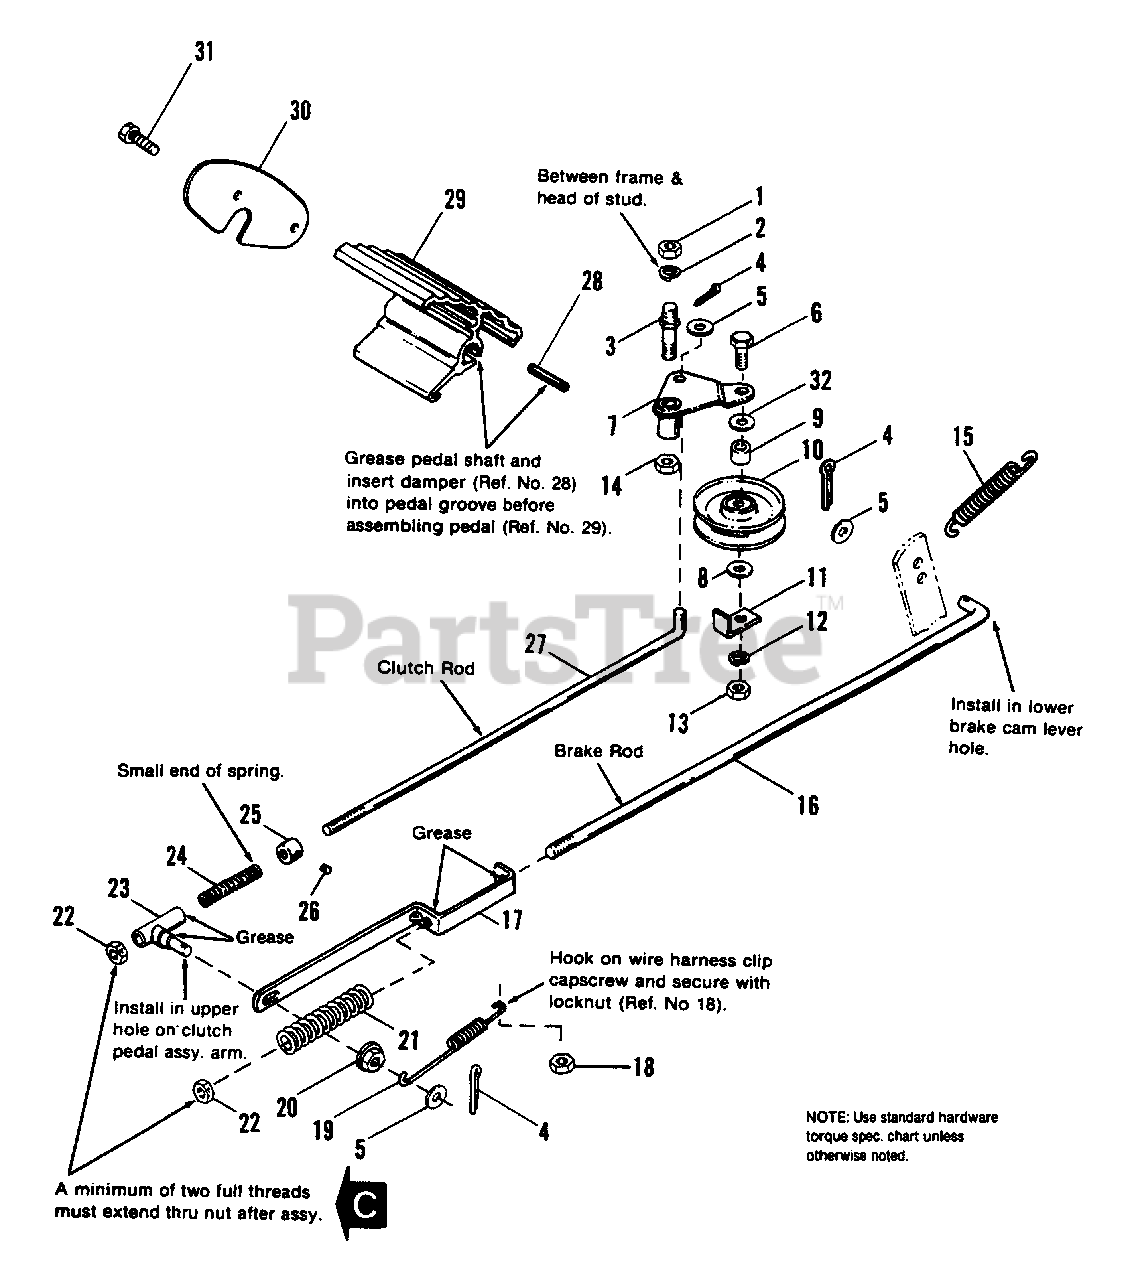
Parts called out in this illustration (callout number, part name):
1	NUT, Hex, 7/16-14
2	LOCKWASHER, 7/16
4	PIN, Cotter, 3/32 x 3/4
5	WASHER, 1/4
6	CAPSCREW, 3/8-16 x 1-1/2
7	IDLER ASSY.
8	WASHER, Plain, 5/16
10	PULLEY ASSY.
11	GUIDE, Belt
12	LOCKWASHER, 3/8
13	NUT, Hex, 3/8-16
14	LOCKNUT, Hex, 7/16-14
15	SPRING, Tension
18	LOCKNUT, Hex, 5/16-18
19	SPRING, Return
20	LOCKNUT, Hex, Flange, 5/16-18
22	LOCKNUT, 5/16-18
23	GUIDE ASSY., Rod
24	SPRING, Compression
25	COLLAR, Set
26	SETSCREW, 1/4-20 x 3/8
27	ROD, Clutch
28	DAMPER, Rubber
29	PEDAL, Foot
30	PLATE, End
31	SCREW, Taptite, 1/4-20 x 5/8
32	WASHER, Plain
